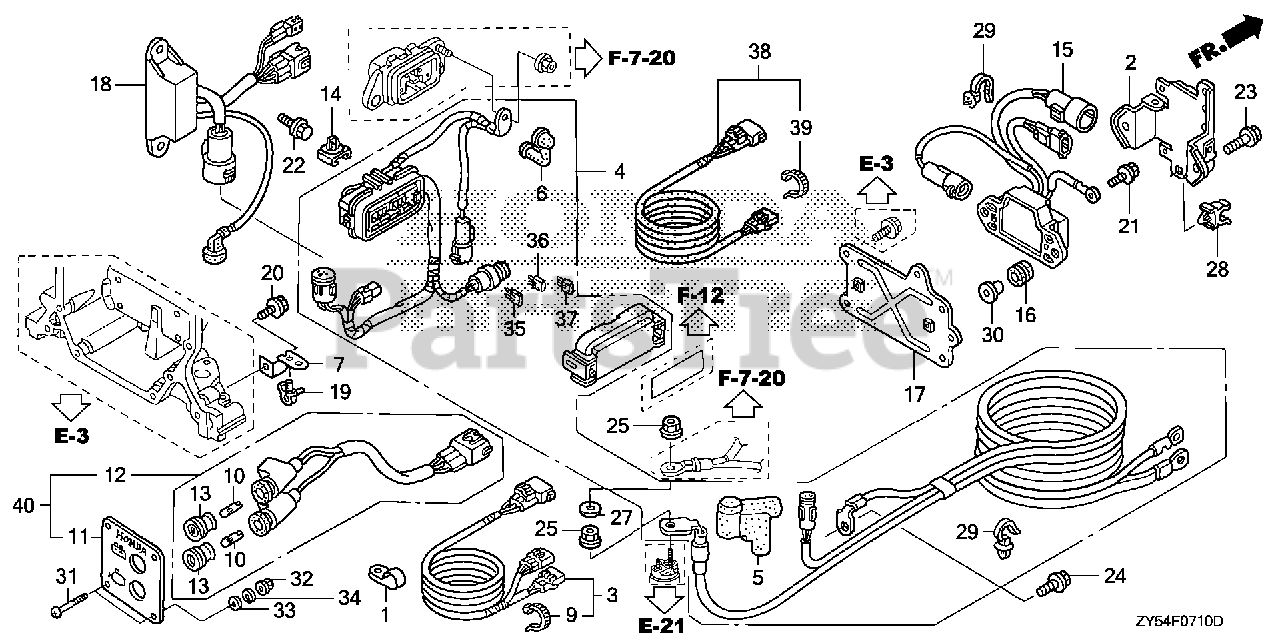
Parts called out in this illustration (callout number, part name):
1	CLAMP F, CABLE
2	BRACKET A, CONNECTOR
3	WIRE ASSY., INDICATOR (DIGITAL)
4	CABLE ASSY., STARTER
5	COVER, STARTER TERMINAL
6	COVER, MAGNETIC SWITCH TERMINAL
7	BRACKET B, CABLE
9	TIE, CABLE (2.4X92) (NATURAL)
10	BULB, WEDGE BASE (T6.5) (12V 3W)
11	PANEL, INDICATOR (2-BULB)
12	LAMP ASSY., INDICATION (2-BULB)
13	LENS, SPEEDOMETER PILOT
14	CLIP, CONNECTOR HOLDER (B)
15	RELAY ASSY., POWER TILT
16	GROMMET, RELAY
17	BRACKET, RELAY
18	RELAY ASSY., MAIN
19	CLIP, BRAKE PIPE (A)
20	BOLT, FLANGE (6X14) (CT200)
21	BOLT, FLANGE (6X12)
22	BOLT, FLANGE (6X16)
23	BOLT, FLANGE (6X22)
24	BOLT, FLANGE (8X18)
25	NUT-WASHER (8MM)
27	WASHER, PLAIN (8MM)
28	CLIP, FUEL TUBE (14) (NOT AVAILABLE)
29	CLIP, HARNESS BAND (145MM) (BLACK)
30	COLLAR, MODULE IGNITION CONTROL CASE (CDI)
31	SCREW, PAN (5X40)
32	NUT, FLANGE (5MM)
33	WASHER, PLAIN (5MM)
34	WASHER, SPRING (5MM)
35	FUSE, MINI (10A)
36	FUSE, MINI (15A)
37	FUSE, MINI (30A)
38	WIRE ASSY., INDICATOR (3P/6P) (ANALOG)
39	TIE, CABLE (2.4X92) (NATURAL)
40	PANEL ASSY., INDICATOR
